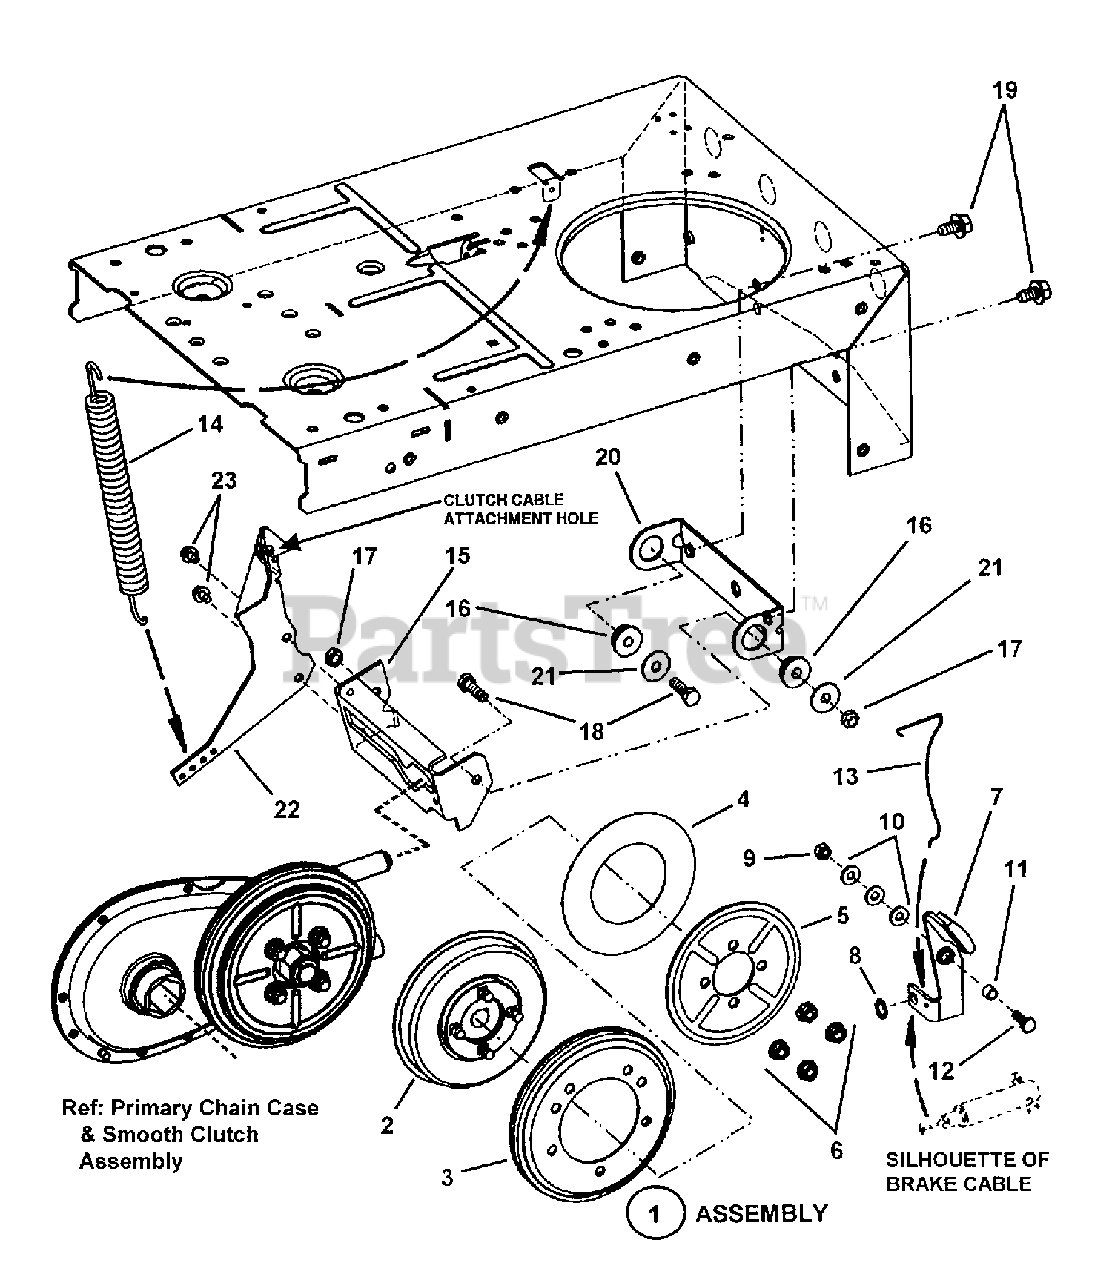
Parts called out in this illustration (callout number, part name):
1	ASSEMBLY, Smooth Clutch
2	ASSEMBLY, Driven Disc Hub
3	DISC, Driven
4	WASHER, Thrust
5	PLATE
6	NUT, 5/16-18 Hex Flange Lock
7	ASSEMBLY, Brake Lever
8	RING, 3/8" External Retaining
9	NUT, 1/4-28 Hex Top Lock
10	WASHER, 1/4 Flat
11	SPACER
12	SCREW, 1/4-28 x 1" Hex Head Cap Grade 5
13	SPRING, Brake Return
14	SPRING, Clutch Brake
15	LIFT, Yoke
16	BEARING, Yoke
17	NUT, 5/16-24 Hex Center Lock
18	SCREW, 5/16-24 x 1" Hex Head Cap, Grade 5
19	SCREW, 3/8-16 x 5/8" Hex Washer Self-Tap
20	COLLAR, Yoke
21	WASHER, 5/16 Flat
22	ARM, Yoke
23	SCREW, 1/4-20 x 3/8" Hex Washer Self-Tap
